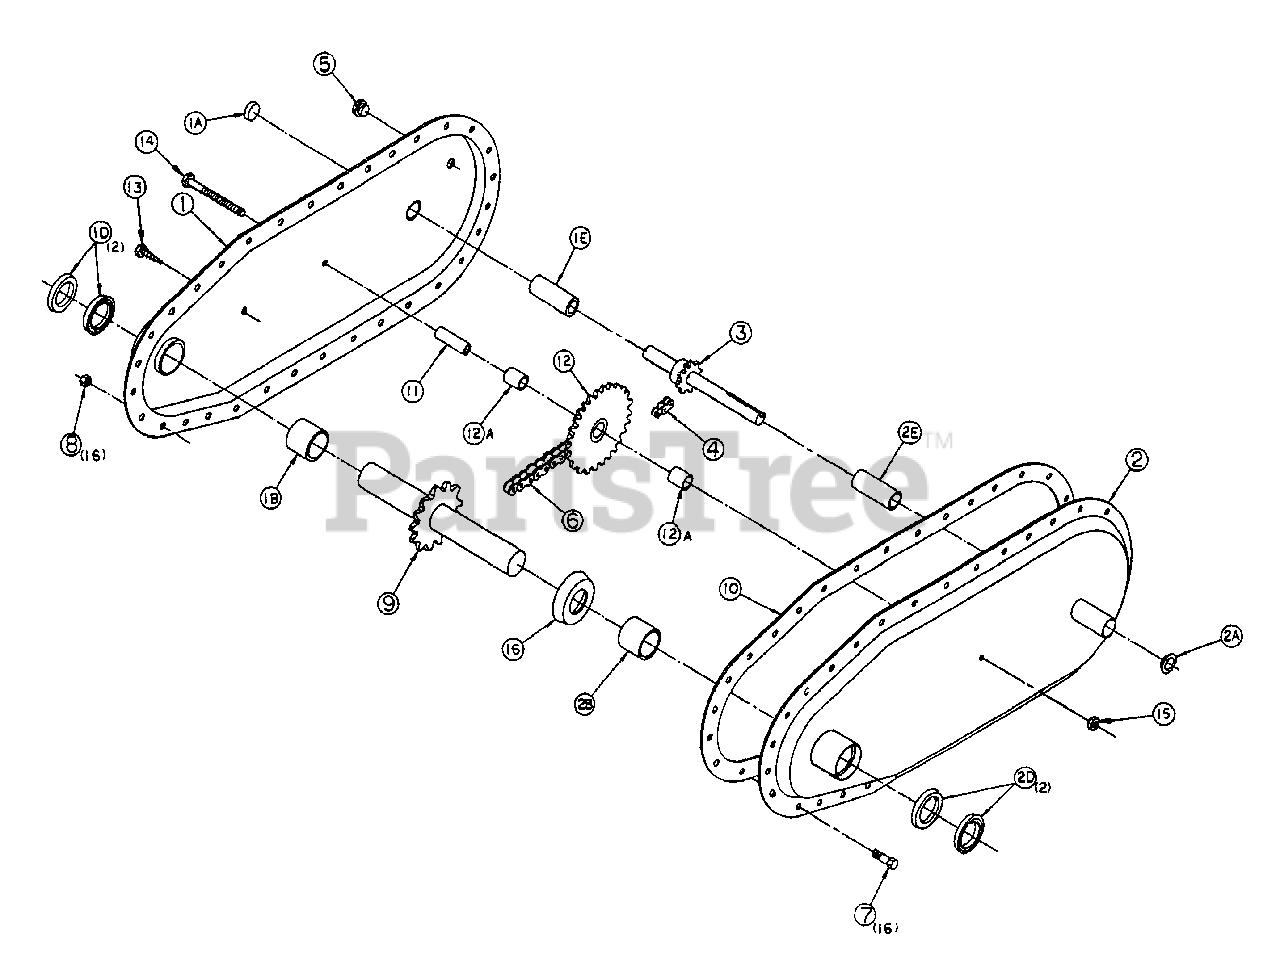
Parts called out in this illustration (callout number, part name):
1	R.H. Case Half Assembly
1A	Soft Plug
1B	Tine Shaft Bearing
1D	Tine Shaft Seal
1E	Bronze Bearing
2	L.H. Case Half Assembly
2A	Drive Shaft Seal
2B	Tine Shaft Bearing
2D	Tine Shaft Seal
2E	Bronze Bearing
3	Drive Assembly Shaft
4	Roller Chain #35-50 Pitches
5	Oil Plug
6	Roller Chain #40-40 Pitches
7	1/4-20 x 1/2" Whiz Lockscrew
8	1/4-20 Whiz Locknut
9	Tine Shaft Assembly
11	Inner Race
12	Idler Sprocket Assembly
12A	Idler Sprocket Bearing
13	1/4 x 3/4" Self Tapping Screw
14	5/16-18 x 2-1/4" HHCS
15	5/16-18 Nylok Locknut
16	Tine Shaft Spacer
